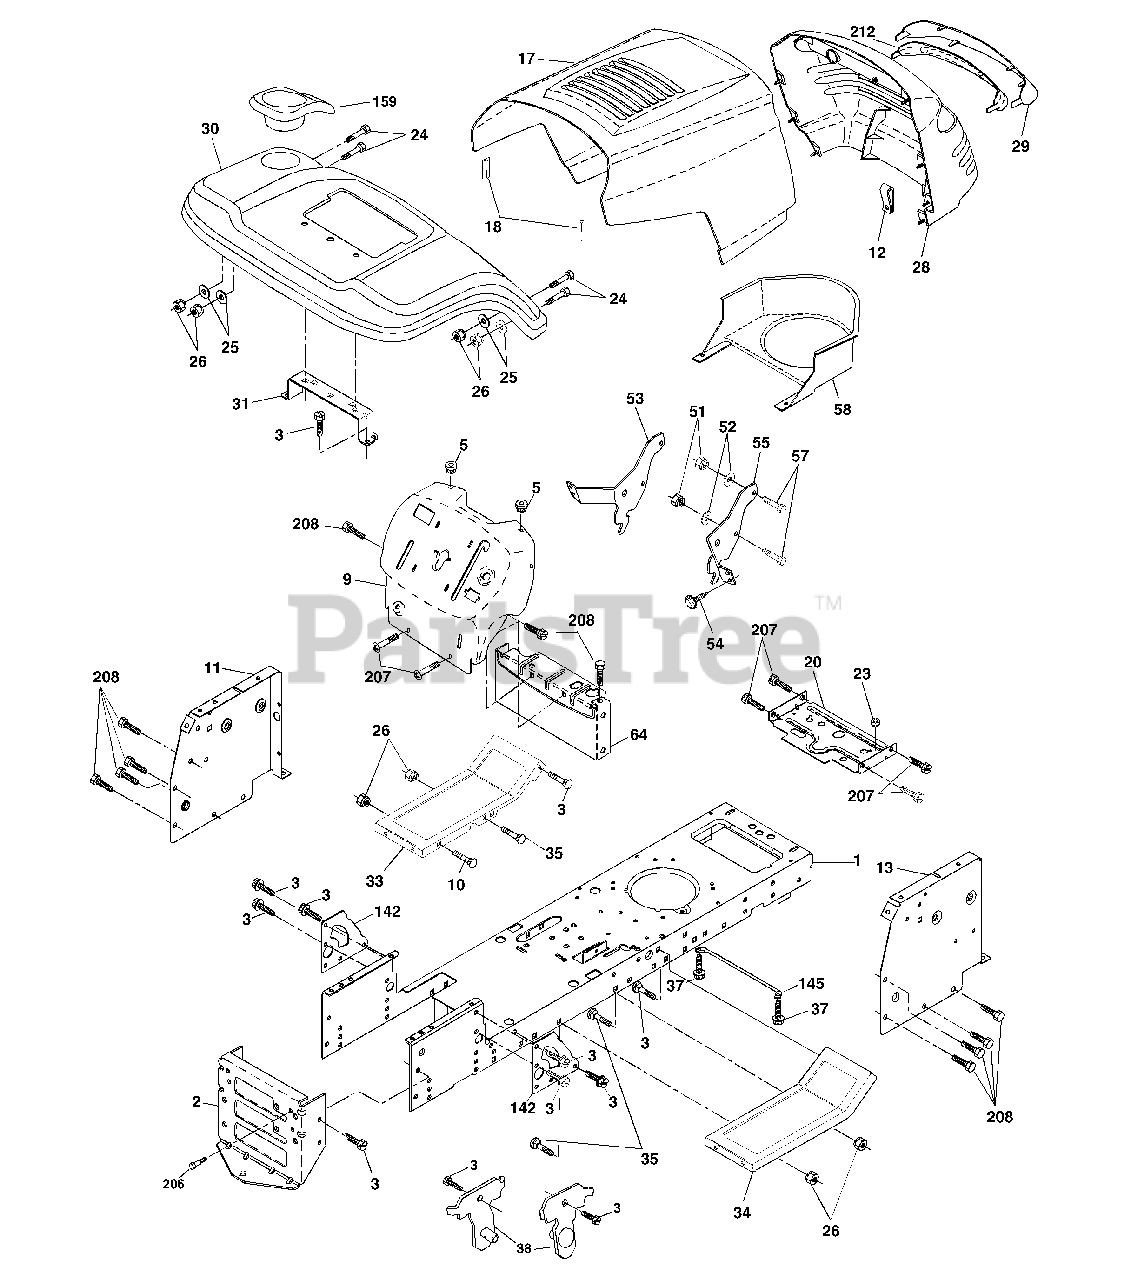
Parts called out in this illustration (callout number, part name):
1	Chassis stamping
2	Drawbar, 12 Ga.
3	Screw 3/8-16x3/4
5	Bumper Hood/Dash
9	Dash Slkscr
10	Bolt Carriage 3/8-16 x 1
11	Panel Dash Lh
12	Clip Tinnerman
13	Panel Dash Rh
17	Hood LT/PL
18	Bumper Hood
20	Plate Mtg Battery Fuel Tank Fr
24	Bolt Fin Hex 3/8-16 Unc x 1 Gr. 5
25	Washer 13/32 X 13/16 X 12 Ga
26	Nut Lock Hex w/Ins. 3/8-16 Unc
28	Grille/Lens Asm
29	Lens
31	Bracket Fender
33	Footrest Pnt Lh
34	Footrest Pnt Rh
35	Bolt Rdhd Sht Sqnk 3/8-16 x 3/4
37	Screw Thdrol 6/16-18 x 1/2 TYT
38	Bracket Asm Pivot Mower Rear
51	Nut Lock w/Insert 1/4-20 Unc
52	Washer 9/32 x 7/8 x 16 Ga.
53	Bracket Grille Lh
54	Screw Hex Wsh 8-18 x 7/8
55	Bracket Grille Rh
57	Bolt Hex 1/4-20 x 3/4
58	Air Duct Engine P/L
64	Dash Lower STLT
142	Plate Reinforcement STLT
145	Rod Pivot Chassis/Hood
159	Cupholder Stlt Grey
206	Bolt Shoulder 5/16-18 TT
207	Screw Thdrol 5/16-18 x 1/2
208	Screw Thdrol 3/8-16 x 1/2
212	Insert Lens Reflective
